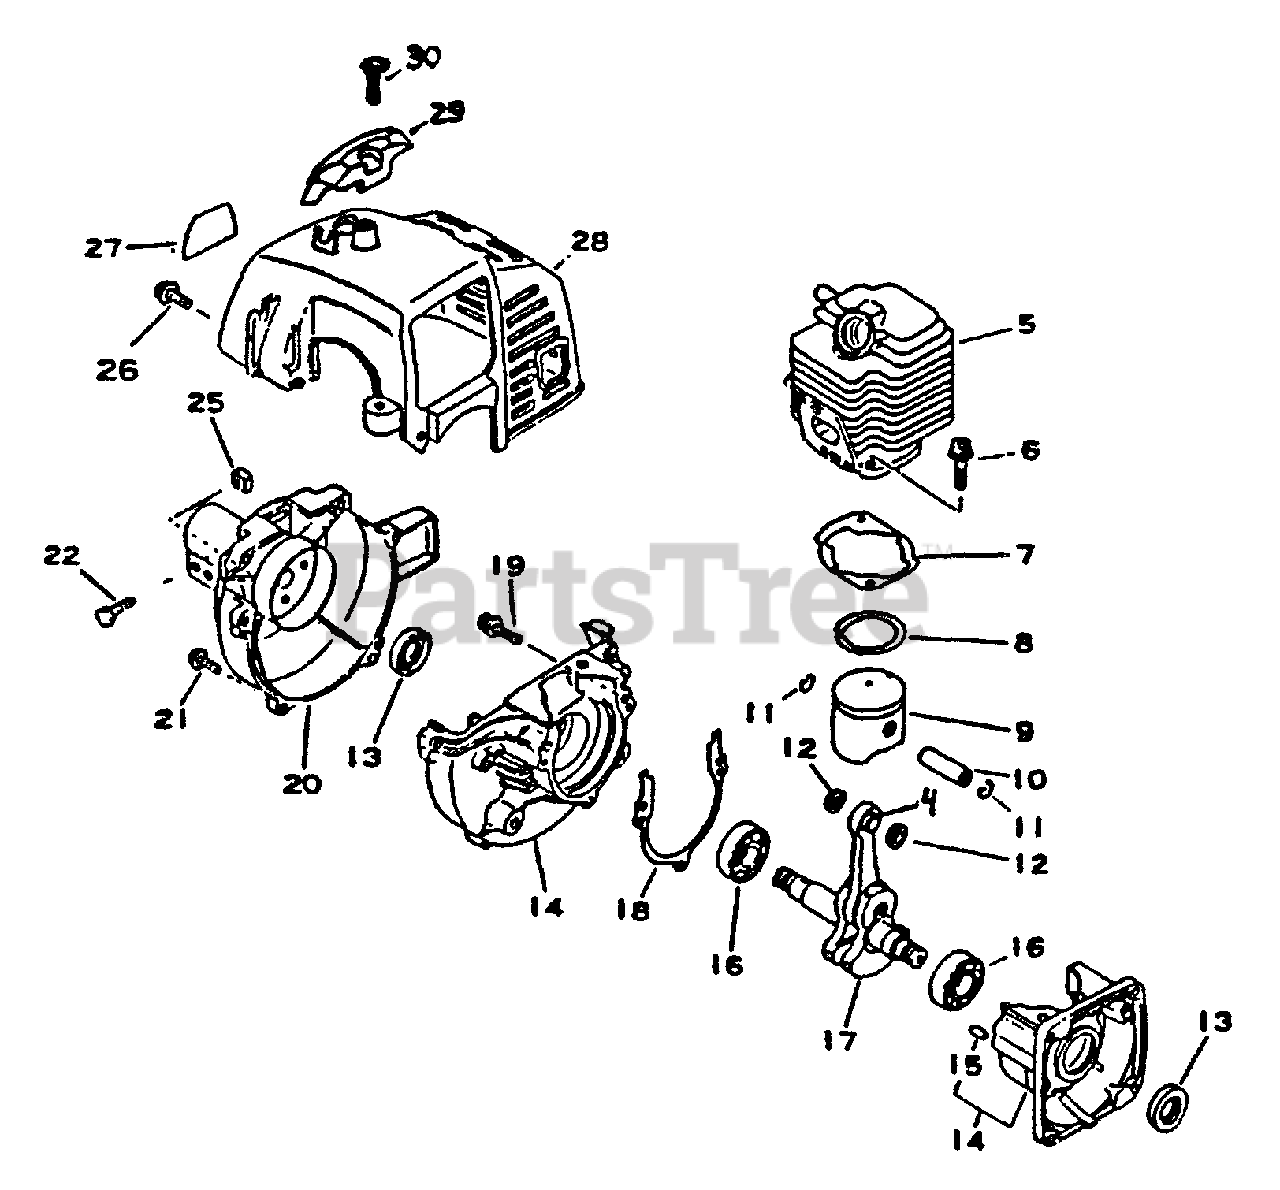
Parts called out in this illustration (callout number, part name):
4	BEARING, NEEDLE
6	BOLT 5×22
7	GASKET, CYLINDER
8	RING, PISTON
9	PISTON
10	PIN, PISTON 8
11	RING, SNAP
12	WASHER, THRUST
13	SEAL, OIL 12
14	CRANKCASE KIT
15	PIN, LOCATING 4
16	BEARING, BALL - 6201 C3
17	CRANKSHAFT ASSY
18	GASKET, CRANKCASE
19	BOLT 5×28
20	COVER, FAN
21	SCREW 4×18
22	BOLT 5×28
25	NUT M5
26	SCREW 4×16
27	LABEL - MODEL
28	COVER, ENGINE
29	GUARD, TOP - BLACK
30	SCREW 5×16
